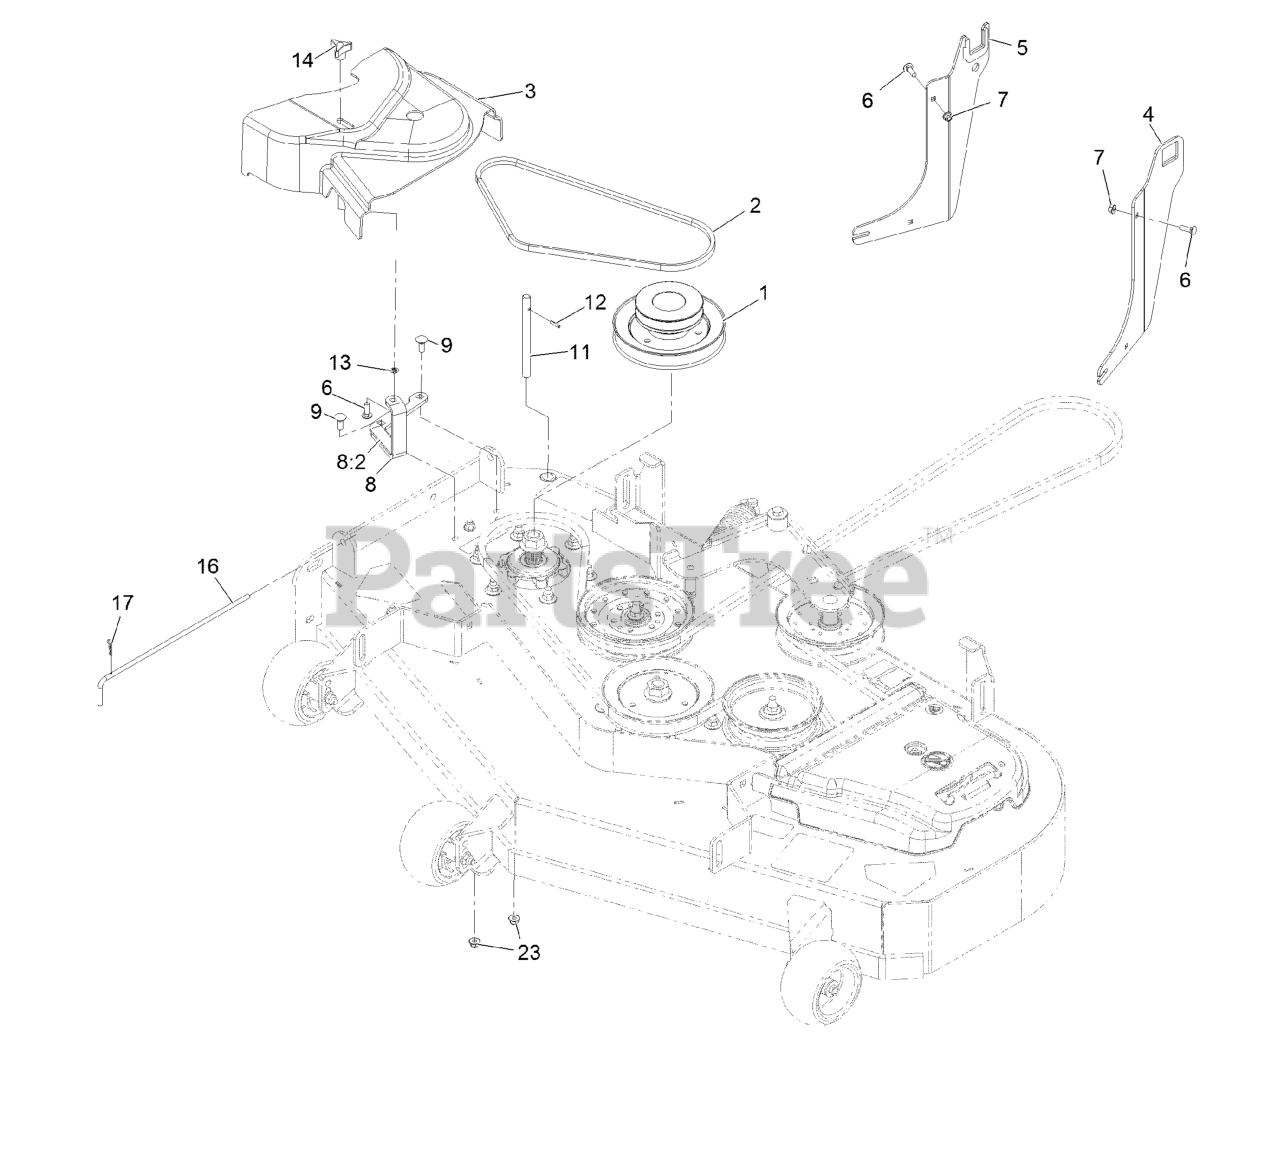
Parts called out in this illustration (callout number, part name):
1	JACKSHAFT-UV DRIVE, 484 SPLINED
3	COVER-BELT, UV 48
4	BRACKET ASM, LH
5	BRACKET ASM, RH
6	BOLT-CARR
7	NUT-HF, NI
8	ASM-CVR BRKT W/DECAL
8:2	DECAL-DANGER
9	BOLT-CARR
11	SHAFT-CATCHER, GRASS
12	PIN-ROLL
13	RING-RETAINING, BOLT
14	KNOB-3 PRONG
16	PIN,CHUTE PIVOT
17	PIN-COTTER
23	Nut-Nyloc 3/8-16 Flg
